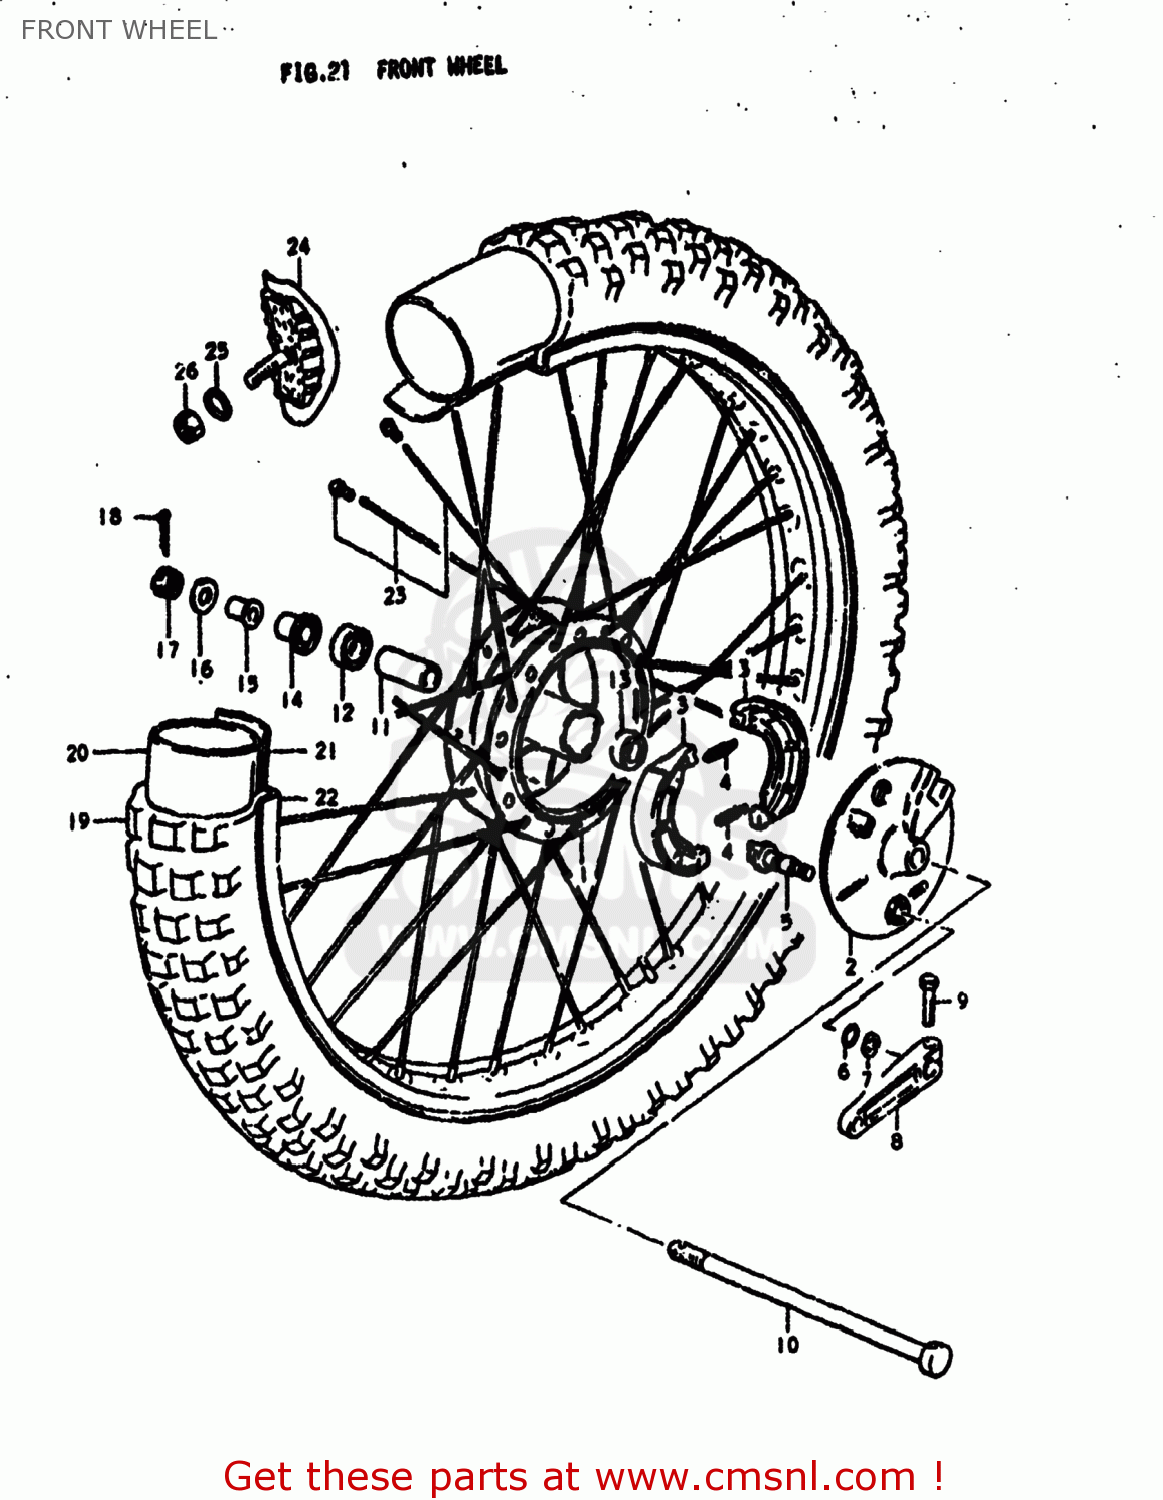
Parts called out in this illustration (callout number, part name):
1	HUB,FRONT
2	PANEL,FRONT HUB
3	SHOE,BRAKE (MCA)
4	SPRING
5	CAM,FRONT BRAKE
6	O-RING,BOSS
7	WASHER (15X24X1.6)
8	LEVER,FRONT BRAKE CAM
9	BOLT
10	AXLE,FRONT
11	SPACER (12.6X19X52)
12	BEARING, RH
13	BEARING
14	SPACER,FRONT AXLE,RIGHT
15	SPACER,FRONT AXLE,LEFT
16	WASHER
17	NUT, REAR AXLE
18	COTTER PIN
19	TIRE,FRONT
20	TUBE,INNER
21	PROTECTOR,WHEEL,INNER
22	RIM,FRONT WHEEL
23	SPOKE SET,FRONT
24	STOPPER,BEAD
25	WASHER
26	NUT
